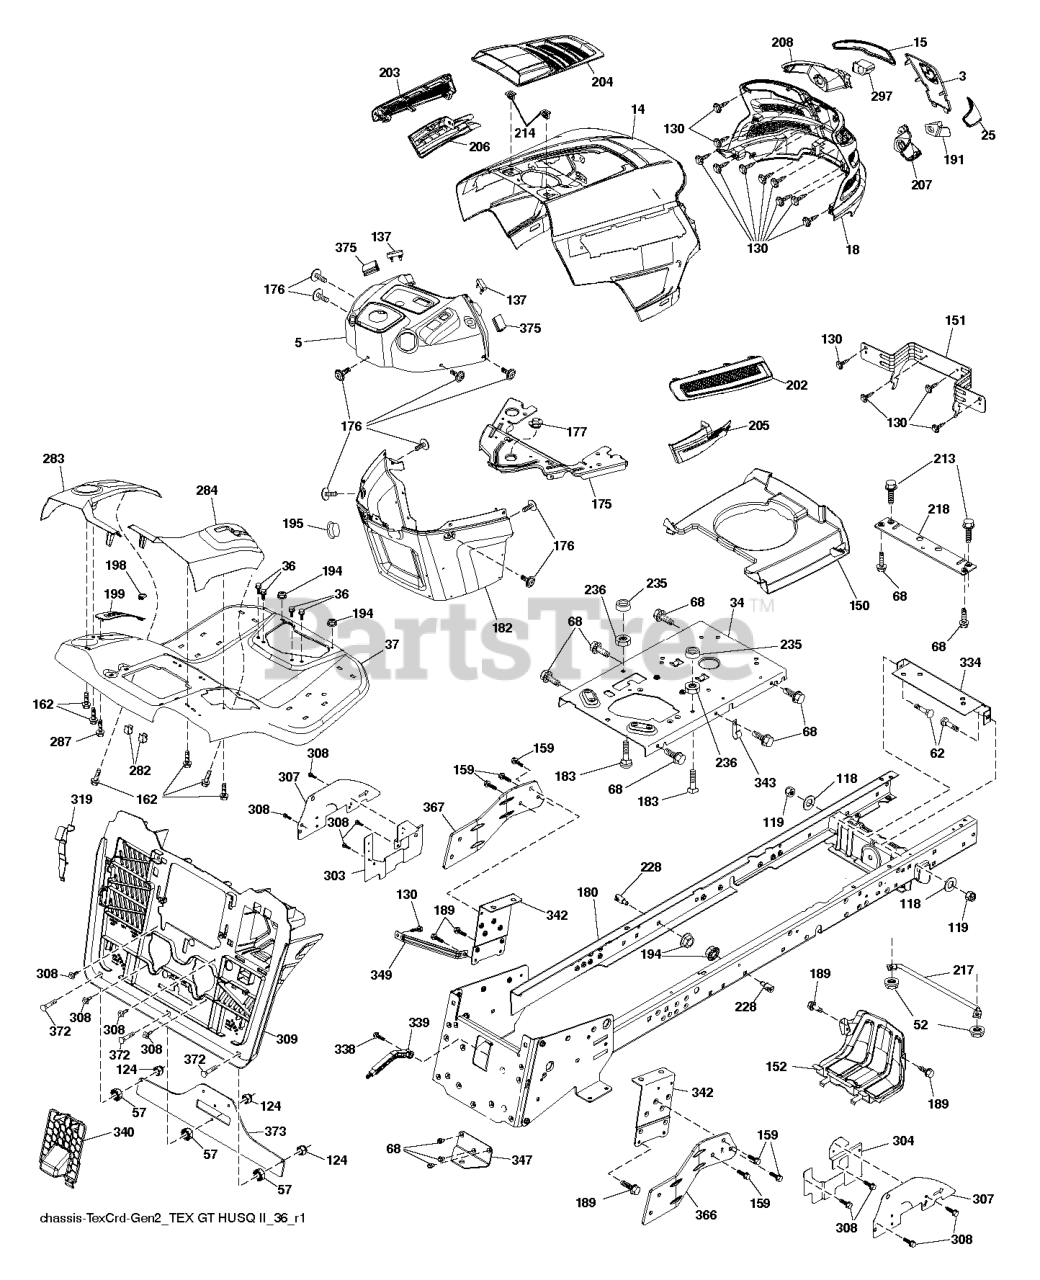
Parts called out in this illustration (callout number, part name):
3	APPLIQUE.SUBASM.GT.HUSQ.II
5	DASH.GT.HUSQTX.SM.M.RS.CH.498
14	HOOD.ASM.HUSQVARNA.GT.TEX.ORAN
15	LENS.HEADLIGHT.LH.GTII.2011
18	GRILLE.SUBSTRATE.2011.
25	LENS.HEADLIGHT.RH.GTII.2011
34	PLATE.ENGINE.10GA.CRD.GENII
36	SCREW 5/16"
37	FENDER.TEX.SRD.CRD.BASE
52	LOCKNUT
62	BOLT D
68	SCREW LT
118	WASHER
130	SCREW.#10 X 0.750.BOS
137	BUMPER DASH
150	AIR.DUCT.GTV.BLACK
151	BRACKET.PIVOT.HOOD.GT.HUSQ.II
152	SHIELD.BROWNING.PNT.GT.V2
159	SCREW, 3/8-16X3/4
162	SCREW.HI-LO.CONSOLE
175	PLATE.CROSSMEMBER.HUSQ
176	SCREW.#10-24X5/8.RN.QU
177	BUSHING, STEERING
180	WELDMENT.CHASSIS.TEX.CRD.GEN.2
182	DASH LOWER.HUSQ.PRED NO CRUISE
183	BOLT.5/16-18X1-1/4 FULL THD
189	SCREW
191	INSERT.REFLECTIVE.RH.HUSQ.GTII
194	NUT LOCK HEX FLANGE 5/16-18
195	PLUG.HOLE.DASH.LOWER.12V.BLK
198	INDICATOR.DECK.LIFT.RED
199	PLATE DECK LIFT
202	VENT.SIDE.RH.GT.HUSQ.II.
203	VENT.SIDE.LH.GT.HUSQ.II.498
204	VENT.TOP.ASM.HUSQ.GT2
205	SIDE.TRIM.RH.GT.HUSQ.II
206	SIDE.TRIM.LH.GT.HUSQ.II.GRAY
207	BEZEL LIGHT.RH.GT.II.MYLAR
208	BEZEL LIGHT.LH.GT.II.MYLAR
213	BOLT
214	CLIP.RETAINER.TINNER.
217	ROD.PIVOT.HOOD
218	X-PIECE.HOOD.STOP.NON/
228	STUD.FASTNER.W/ANTI-ROTATE
234	BUMPER.HOOD.TEX.HUSQVARNA
235	SPACER FENDER
236	NUT.CENTERLOCK.5/16-
282	CLIP.RETAINER.CONSOLE.LT.HUSQ
283	CONSOLE.DECKLIFT.CRDII.498
284	CONSOLE.PEDAL.HYDRO
287	SCREW 1/4X20
297	INSERT.REFLECTIVE.LH.HUSQ.GTII
303	SHIELD.LWR.LH.LT.30"CRDSRD.PNT
304	SHIELD.LWR.RH.LT30DECK.PNT.BLK
307	SHIELD.UPPER.CRD.SRD.ISO
308	BOLT.5/16-18UNCX3/4 W/SEMS.BLK
309	BACKPLATE.ASM.CRDII.ANTIROTAT
319	LEVER.BAG.CRDII.ANTIROTATION
334	BRACKET.ENGINE
338	BOLT BOLT SHOULDER
339	LEVER LEVER BAGGER
340	BATTERY.DOOR.TEX.CRD.GEN.2,1
342	SUPPORT SUPPORT FENDER
343	CLIP CLIP
347	HITCH TOW
349	BRACKET.SUPPORT.LRVB/CRD
366	BRACKET.RH.FRONT.BAGGER.BLACK
367	BRACKET.LH.FRONT.BAGGER.BLACK
368	FULL.LEVER.BAGGER.TEX.CRD
